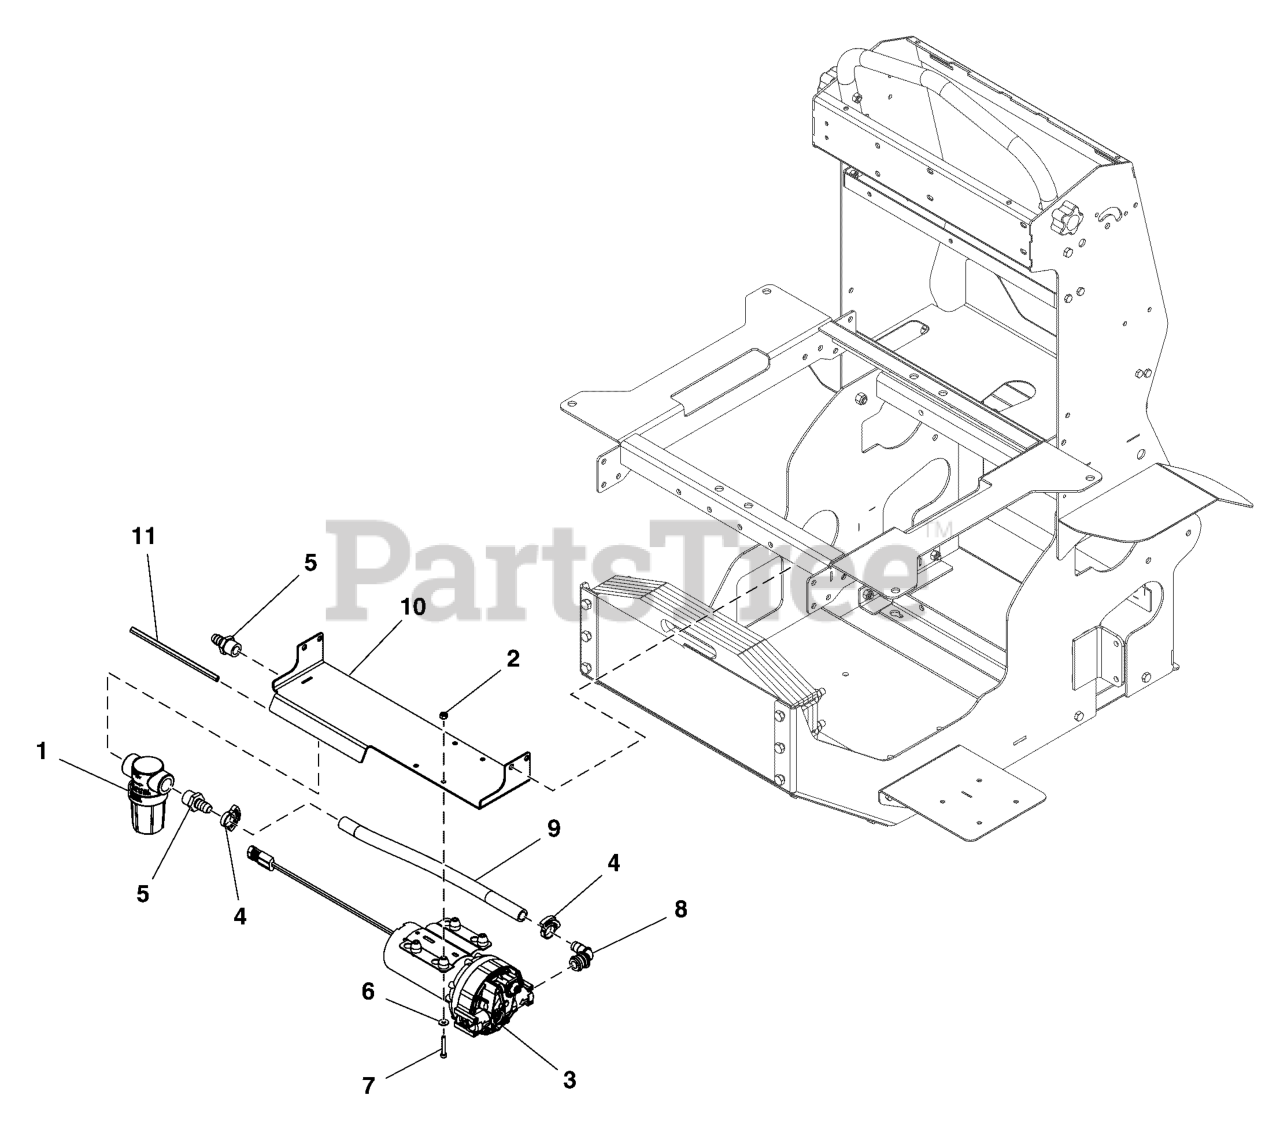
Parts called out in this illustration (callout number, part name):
1	STRAINER, LIQUID, IN-LINE, 50 MESH
3	PUMP, VENTURE
3	PUMP, DELEVAN 5 GPM 5950-117E
4	SNAP GRIP CLAMP .656 - .750 ID
4	CLAMP, PINCH 19.8mm TO 22.6mm
5	FITTING, 1/2 MPT - 1/2 BARB
6	WSHR-STL, FLT .203" X .562" X .040 IS SS188
7	SCR-CAP SH, #10-24 X 1.250" SS188
8	FITTING, ELBOW, 3/4 QA - 1/2 BARB
9	HOSE, PUMP SUCTION, 0.5" ID, 12" LONG
10	WELD, FILTER MOUNT BRACKET
11	TRIM FOR CONSOLE, 7 INCH
11	TRIM FOR CONSOLE HEAVY DUTY, 7 INCH
